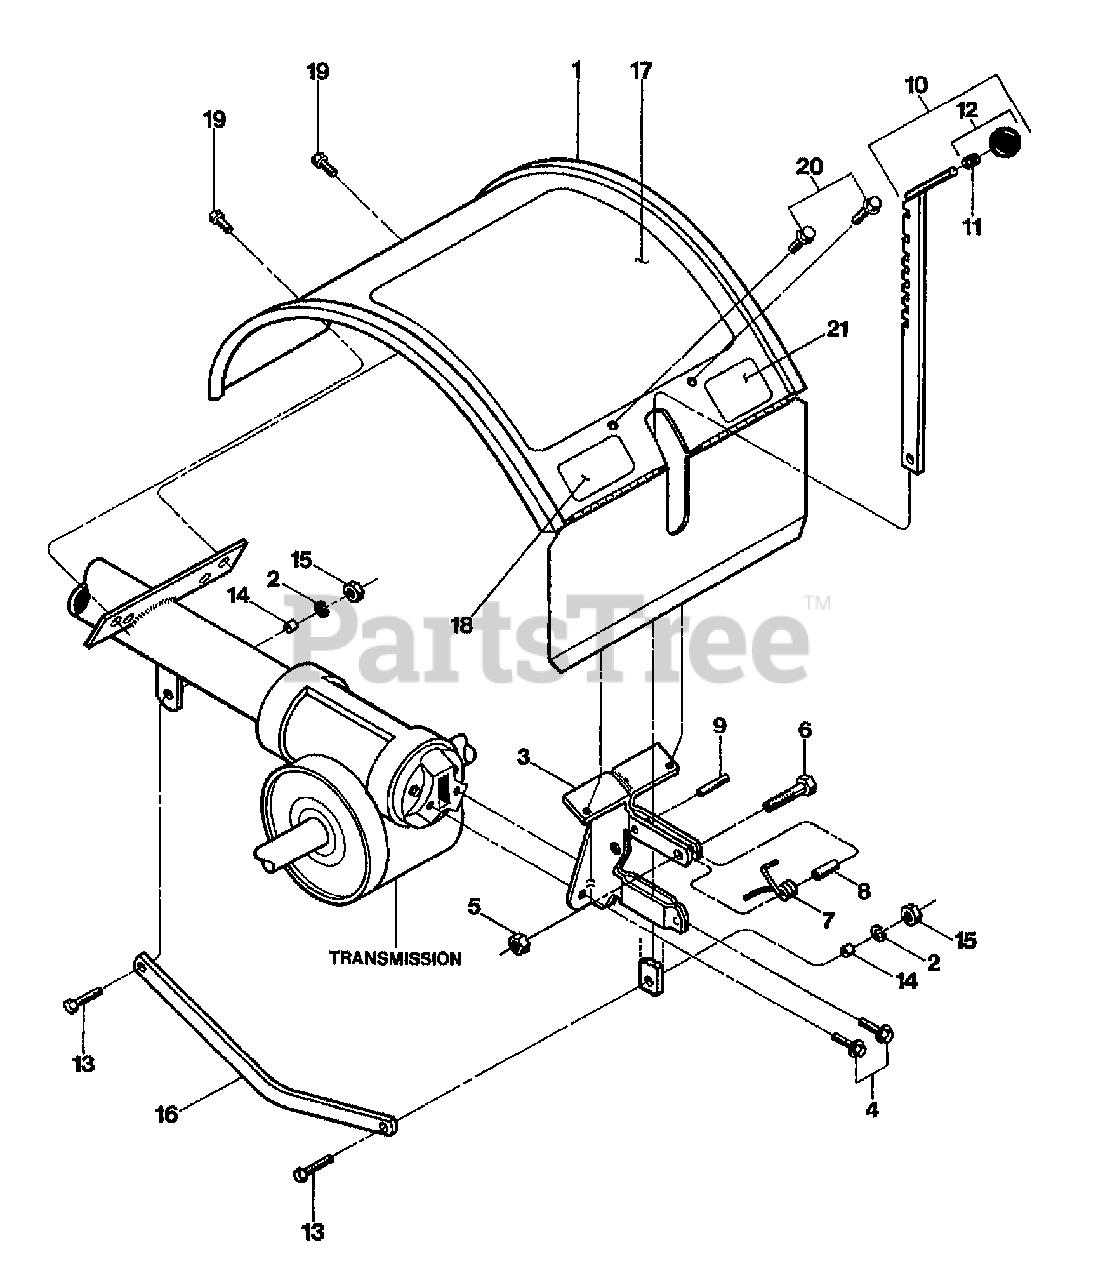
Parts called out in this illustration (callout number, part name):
1	HOOD W/DECAL ECONO OPC (INCL. 17,18, & 21)
2	WASHER-LK .375 @ DEPL
3	BRKT W/ROLL PIN (9308)(INCL. 9)
4	SCR-HFLK 5/16-18X.75 ZP
5	NUT-LK 1/4-20
6	SCR-HH 1/4-20X1.0
7	SPRING-TORSION
8	SPACER-.250X.343X.375
9	PIN-ROLL .25 X 1
10	DEPTH REGULATOR W/KNOB (INCL. 11 & 12)
11	RING-TOLERANCE .5325 ID
12	KNOB-CONTROL (INCL. 11)
13	SCR-HH 3/8-16X1.25
14	BUSHING-.5X.375X.3
15	NUT-HEX 3/8-16 ZP
16	DRAG BAR-BENT
17	DECAL-HOOD OPER INST OPC
18	DECAL-LOGO (MODEL NAME DECAL)
19	SCR-HWH 5/16-18 X .5 STH
20	SCR-HWH 1/4-20 X .5 STH (ATTACHES HOOD TO DEPTH REGULATOR BRACKET)
21	DECAL-TINE WARN SM FRAME
